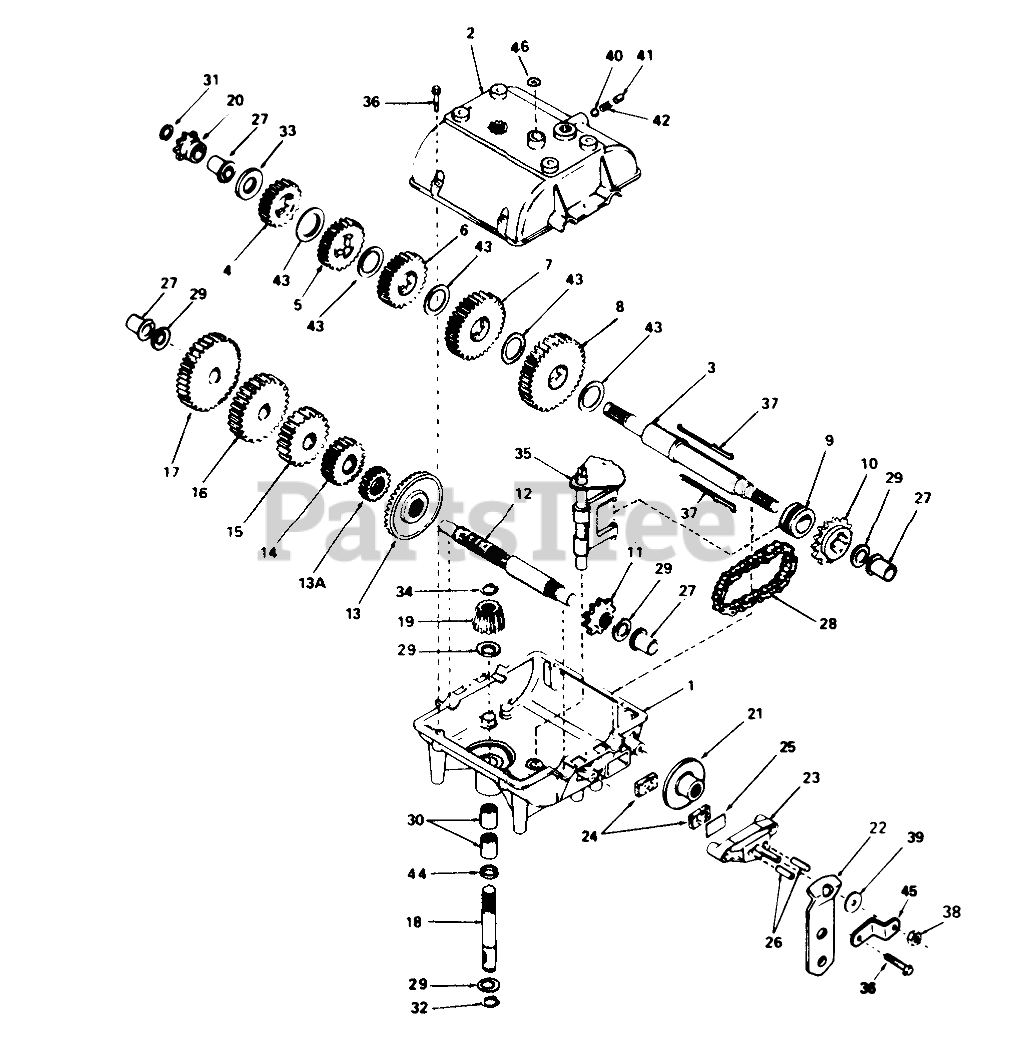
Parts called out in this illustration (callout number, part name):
1	Case-Transmission
2	Cover-Transmission
3	Shaft-Output Brake
4	Gear-Spur 20 teeth
5	Gear-Spur (22 teeth)
6	Gear-Spur, 25 Teeth
7	Gear-Spur, 30 Teeth
8	Gear-Spur, 35 Teeth
9	Collar-Shift
10	Sprocket-18 Teeth
11	Sprocket-9 Teeth
12	Countershaft
13	Gear-Bevel (42Teeth)
13A	Gear-Spur 15 Teeth
14	Gear-Spur, 20 Teeth
15	Gear-Spur, 25 Teeth
16	Gear-Spur (28 teeth)
17	Gear-Spur (30 teeth)
18	Shaft-Input
19	Bevel Pinion-Input
20	Sprocket (8 teeth)
22	Lever-Brake
23	Nozzle-Carburetor
24	Brake Pad
25	Brake Pad Plate
26	Dowel Pin
27	Bushing-Flange
28	Chain-Roller #41
29	Washer
30	Bearing-Needle
31	Piston Asm (.020 O S)
32	Ring-Snap
33	Washer
34	Ring-Retainer
35	Rod and Fork ASM
36	Ring Set (.020 O S)
38	Locknut
39	Washer
40	Ball-Steel
41	Screw-Set
42	Spring
43	Washer
44	O Ring
45	Bracket
46	Cut Seal-Square
